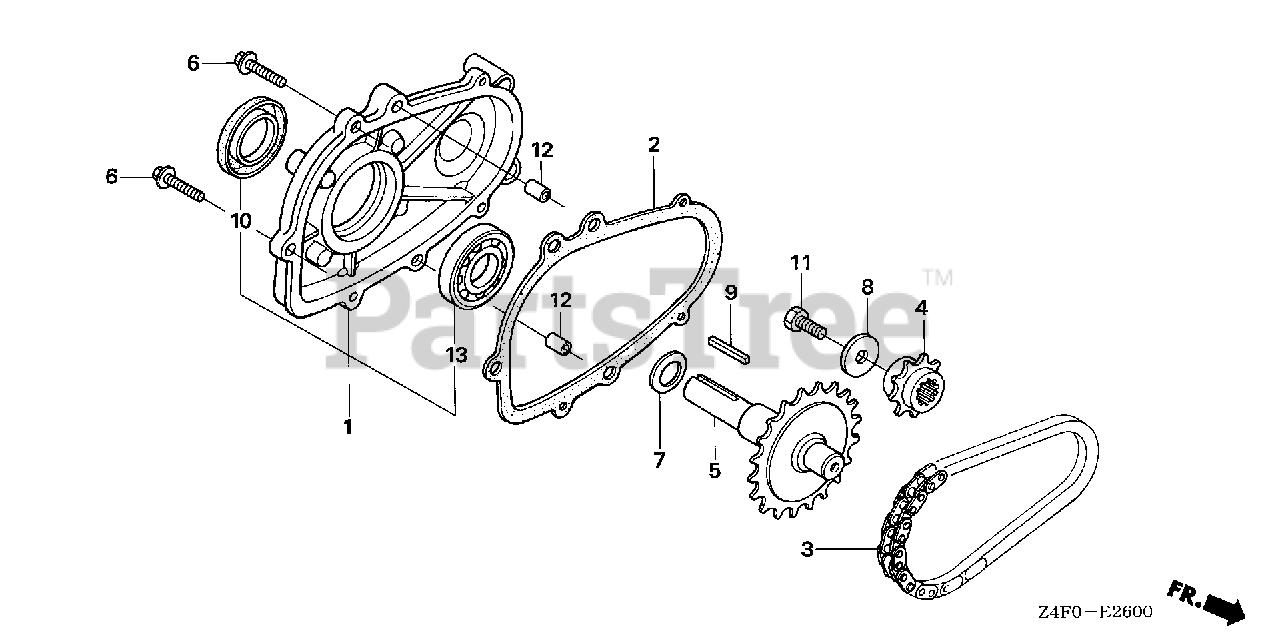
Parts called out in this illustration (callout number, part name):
1	COVER ASSY., CHAIN CASE
2	GASKET, CHAIN CASE COVER
3	CHAIN, P.T.O. DRIVE (DID270S-DHA-36LE)
4	SPROCKET, DRIVE (14T)
5	SHAFT, P.T.O. (28T)
6	BOLT, FLANGE (6X28) (CT200)
7	SPRING, THRUST
8	WASHER (8MM)
9	KEY (5X5X33) (YELLOW)
10	OIL SEAL (25X41X6) (NOK)
11	BOLT, HEX. (8X25)
12	PIN, DOWEL (8X14)
13	BEARING, RADIAL BALL (6205)
